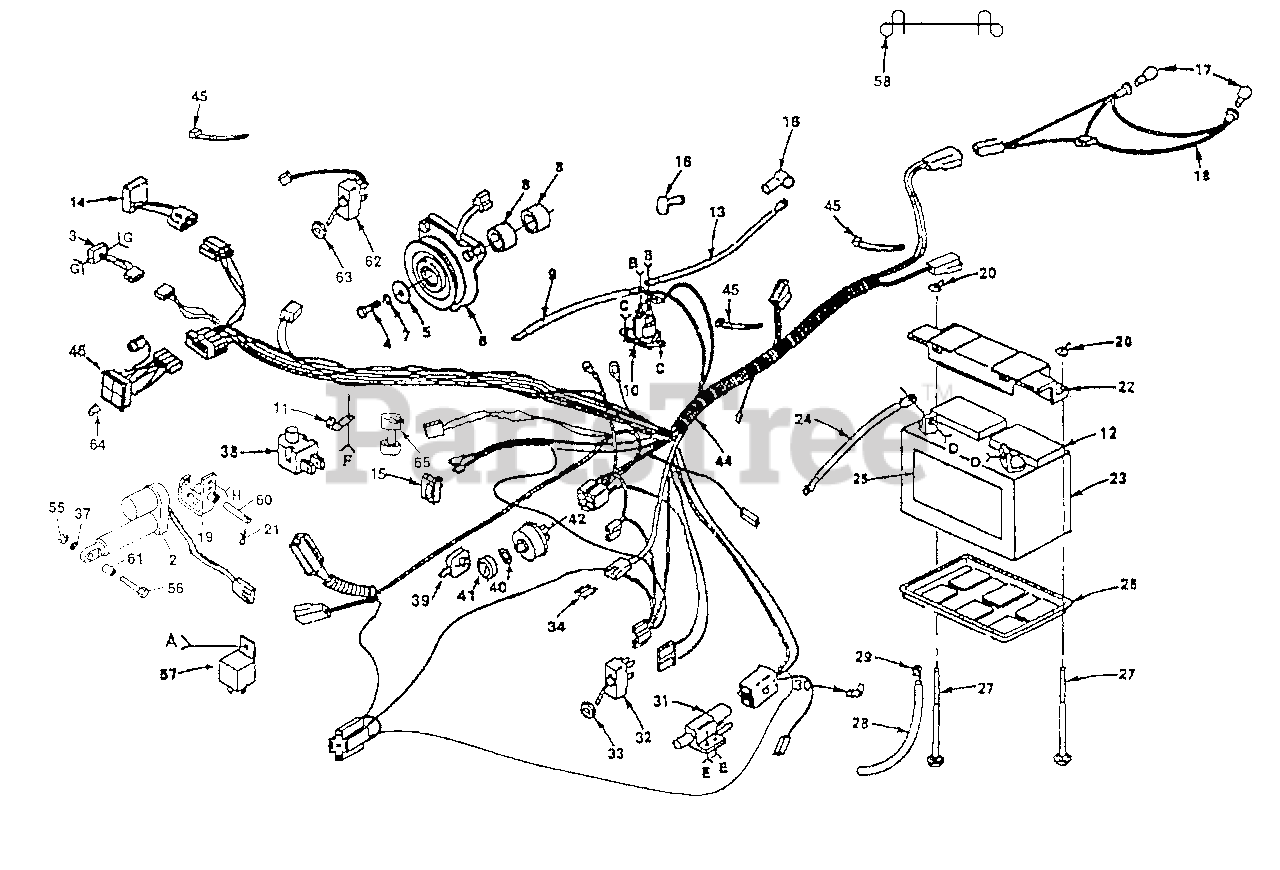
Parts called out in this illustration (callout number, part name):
2	Actuator, Electric
3	Meter, Hour
4	Bolt-Hex 7/16 - 20 x 1-1/2 GR 5
6	Clutch - Electric
7	Washer - Lock 7/16
8	Spacer - Clutch
9	Cable - Battery
10	Solenoid
11	Clip - Insulated
12	Battery Caps
13	Cable - Starter
14	Sensor, Low Voltage
15	Switch - Light
16	Cover-Terminal
17	Bulb - Light
18	Harness - Light Socket
19	Bracket Assembly, Actuator
20	Wing Nut 1/4 - 20
21	Spring, Retainer
22	Guard - Terminal
23	Battery
24	Cable Ground
25	Decal, Battery
26	Tray - Battery
27	Bolt - Carriage 1/4 - 20 x 7-1/2
28	Tube-Plastic
29	Clamp-Hose
31	Switch-Interlock
32	Switch - P.T.O.
33	Nut-Hex
34	Fuse - 30 Amp
37	Washer, Lock 3/8
38	Switch, Seat
40	Nut - Ignition
41	Bezel, Ignition
42	Switch - Ignition
44	Harness - Ignition
45	Cable Tie
46	Light Package
55	Nut, Fin Hex 3/8 - 16
56	Bolt, Fin Hex 3/8 - 16 x 2 1/4
57	Assembly - Relay
60	Pin, Actuator
61	Tube .384 x 1/2 x 1 1/4
62	Switch Assembly, Lift
63	Washer, Lock
64	Bulb, Dashboard, Light
65	Sensor, Low Fuel
